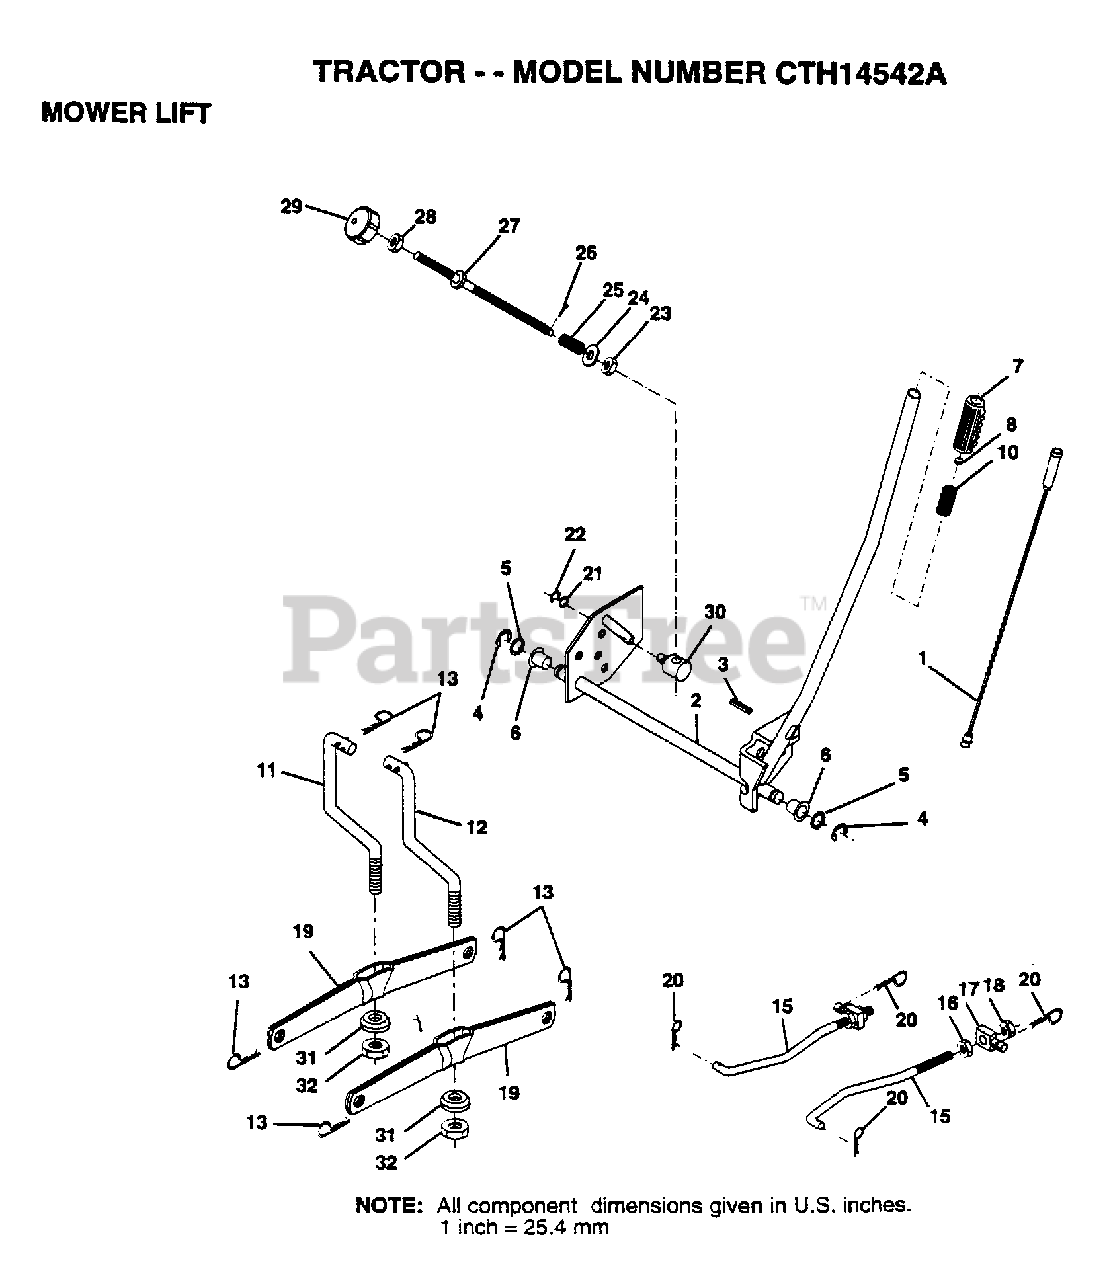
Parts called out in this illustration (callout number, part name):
1	WIRE.ASM.INNER
2	SHAFT.ASM.LIFT.RH
3	PIN GROOVE
5	WASHER
6	NYLON BEARING
7	GRIP
15	LINK.FRONT
16	NUT
17	TRUNION
18	NUT.LK.W/WSH.1/2.
19	ARM SUSP REAR
20	RETAINER.SPRING
21	WASHER
22	KLIP RING
23	NUT T
24	WASHER
25	SPRING.COMP.INF.H
27	ROD.ADJ.LIFT
28	NUT
29	KNOB INF 3/8-16
30	TRUNION LT
31	BEARING PVT LH
32	NUT.CROWNLOCK.3/8
